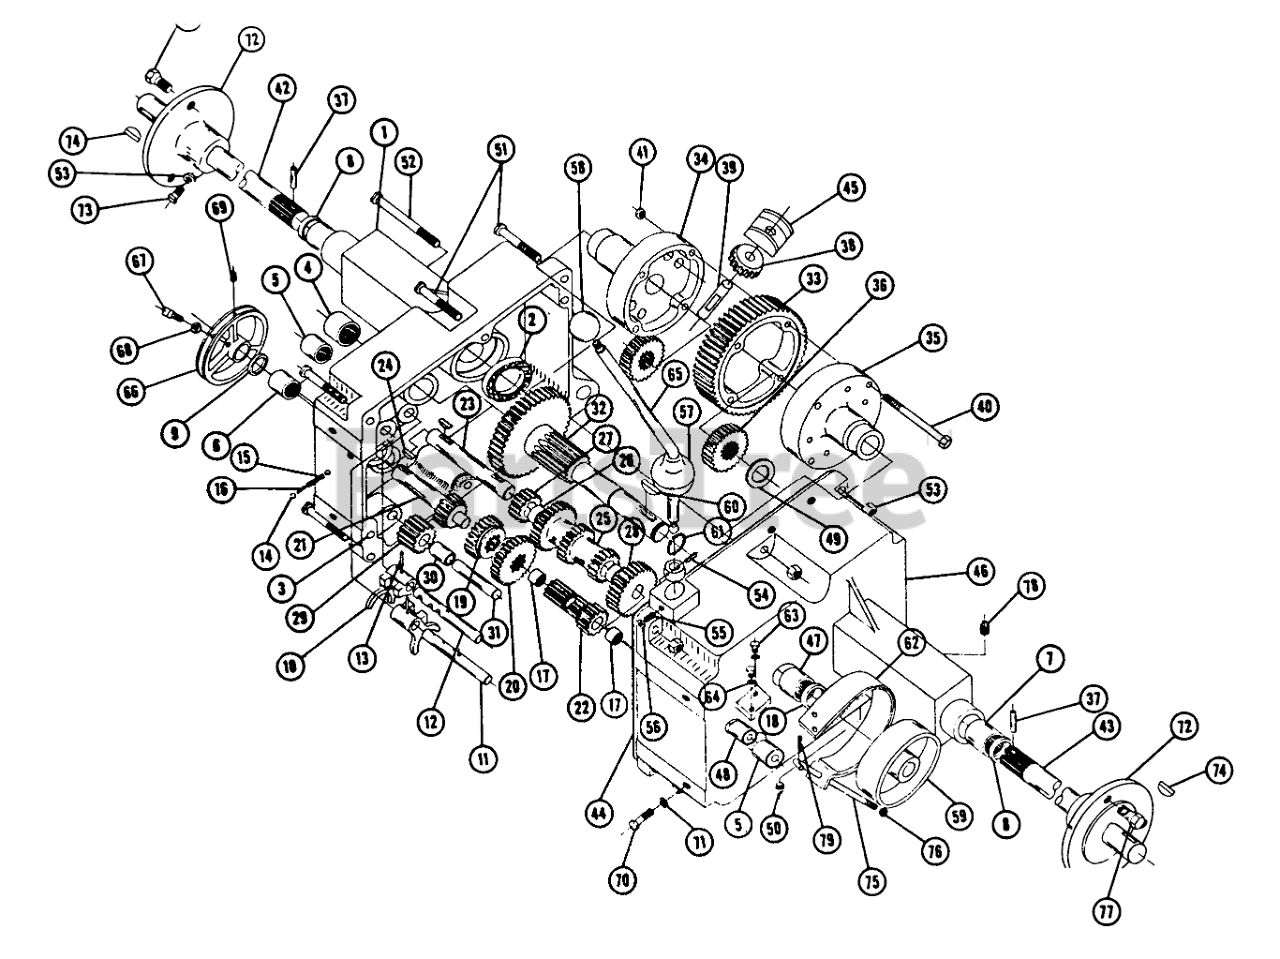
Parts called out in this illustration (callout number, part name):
3	PIN-DOWEL
4	BEARING-NEEDLE
5	BEARING-NEEDLE
10	FORK-SHIFT
11	RAIL-SHIFT
12	RAIL-REAR SHIFT
13	PIN-ROLL
14	BALL-DETENT
16	PIN-SHIFT
17	BEARING-NEEDLE
19	GEAR-HI AND 2ND
20	GEAR-LOW AND REVERSE
22	GEAR
24	Key
26	BUSHING-BRONZE
28	GEAR-CLUSTER SHAFT
29	GEAR/BUSHING ASM-REVERSE IDLER
30	BUSHING
31	PIN-DIFFERENTIAL
33	GEAR DIFF BULL
34	DIFF CASE RH
40	Bolt-Hex 3/8-16 x 4
41	Nut-Hex Lock 3/8-16
42	Clevis
44	GASKET-TRANSMISSION
45	BLOCK
50	Plug 3/8 Pipe
51	Bolt, 3/8 16 x 2
52	Bolt-Hex 3/8-16 x 3 1/2
54	Roll Pin
55	SETSCREW
56	Nut-Nylok
57	COVER-DUST
60	KEY-WOODRUFF
61	Snap Ring 1- Shaft
63	Bolt-1/4-20 x 5/8
64	Lockwasher
65	Ass-y. Shift Stick
67	Set Screw Sq. Hd. 5/16-18 x
68	Nut 5/16-18 Jam
69	Set Screw 5/16-18 x 5/16
70	Bolt 3/8-16 x 1
71	Lockwasher
73	Set Screw, 3/8-16 x 1-1/4
75	Rod
76	Nut 3/-16 Elastic Stop
77	BOLT-LUG, WHEEL
78	Plug 1/4 Pipe
